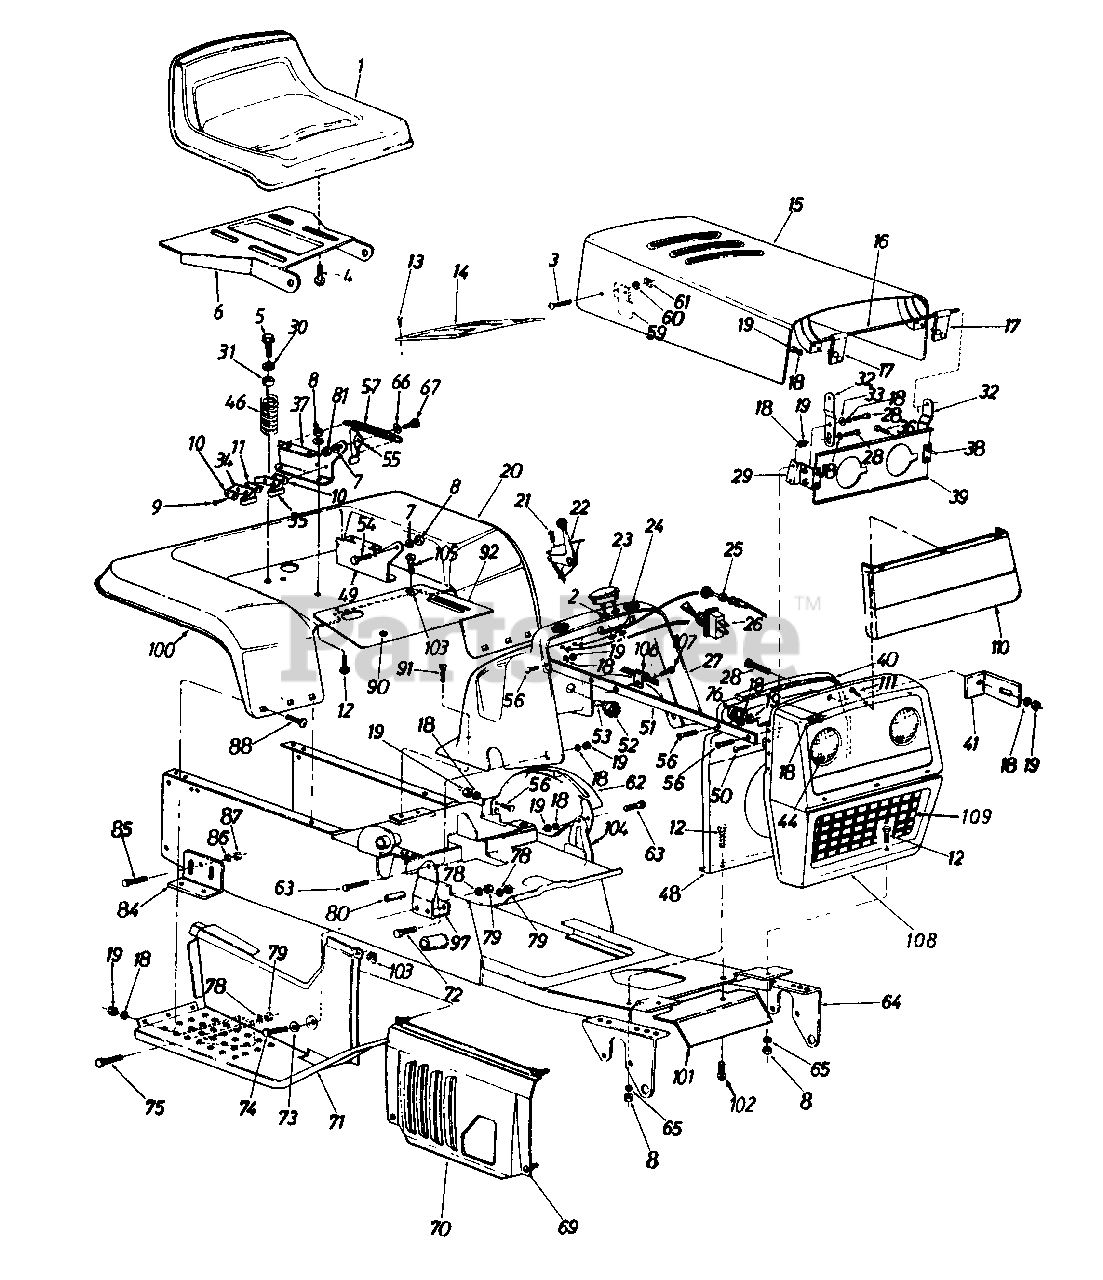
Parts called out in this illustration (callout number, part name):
1	Seat Ass'y. (Yellow)
2	L-Wash. .190" I.D.
3	Truss Hd. Mach. Scr. #10-24 x .38" Lg.
4	Hex Wash. Hd. Self-Tap Scr. 3/8-16 x .75" Lg.
5	Hex Wash. Hd. Tap Scr. 5/16-18 x .75" Lg.
7	L-Wash. 5/16" I.D.
8	Hex Nut 5/16-18 Thd.
9	Hex Wash. Hd. AB-Tap Scr. #8 x .5" Lg.
10	Insulator Plate
11	Insulator Boss Plate
12	Hex Bolt 5/16-18 x .75" Lg.
13	Self-Tap Oval Hd. Scr. 1/2" Lg.
14	Dash Panel Cover
17	Hood Hinge Ass'y.
18	L-Wash. 1/4" I.D.
19	Hex Nut 1/4-20 Thd.
22	Throttle Control
23	Ammeter
24	Rubber Bumper
25	Choke Control
26	Light Switch
27	Dash Panel
28	Hex Bolt 1/4-20 x .62" Lg.
29	Hood Support Brkt. Ass'y.- R.H.
30	Fl-Wash..344" I.D. x .875"
31	Bushing
34	Safety Switch (Seat)
35	Safety Switch (Seat)
36	Hex Bolt 1/4-20 x .38" Lg.
38	Hood Support Brkt. Ass'y.- L.H.
41	Heat Shield Brkt.
44	Head Lamp
46	Compression Spring 4.5" Lg.
50	Truss Mach. Scr. 1/4-20 x .75"
53	Ignition Key
54	Shld. Bolt .437" Dia. x .162"
55	Seat Lift Bracket
56	Hex Bolt 1/4-20 x .75" Lg.
57	Extension Spring 5.31" Lg.
59	Hood Spring
60	L-Wash #10
61	Hex Nut #10-24 Thd.
62	Speed Control Guide
63	Truss Mach. Scr 1/4-20 x 75"
66	Spr. Wash 445" I.D. x 75"
67	Shld. Bolt .437" Dia. x .268"
69	Truss Mach. Scr. #10-24 x .5" Lg.
73	Fl-Wash..385" I.D x .62" O.D
74	Hex Bolt 3/8-16 x 3.00" Lg.
75	Hex Bolt 3/8-16 x 1.00" Lg. Grade 5
76	Snap Bushing
78	L-Wash. 3/8" I.D.
79	Hex Nut 3/8-16 Thd.
80	Spacer .375" I.D. x 62" O.D x 2" Lg.
81	Hex Nut 5/16-18 Thd. (Gr 5)
84	Transaxle Support Brkt.
85	Rd. Hd. Rib Neck Scr. 3/8-24
86	L-Wash, 3/8" I.D.
87	Hex Nut 3/8-24 Thd. (Gr. 5)
88	Carr. Bolt 1/4-20 x .50" Lg.
90	Snap Bushing
91	Hex Wash. Hd. Tap Scr. 1/4-20 x .5" Lg.
103	Speed Nut #10-24 Thd.
104	Dash Panel Mtg. Brkt.- L.H.
105	Truss Mach. Scr. #10-24 x .5"
106	Clamp
107	Self-Tap Scr. 5/16 x 5" Lg.
110	Headlight Bezel
111	Hex Wash Hd Scr. #8 x .5" Lg.
